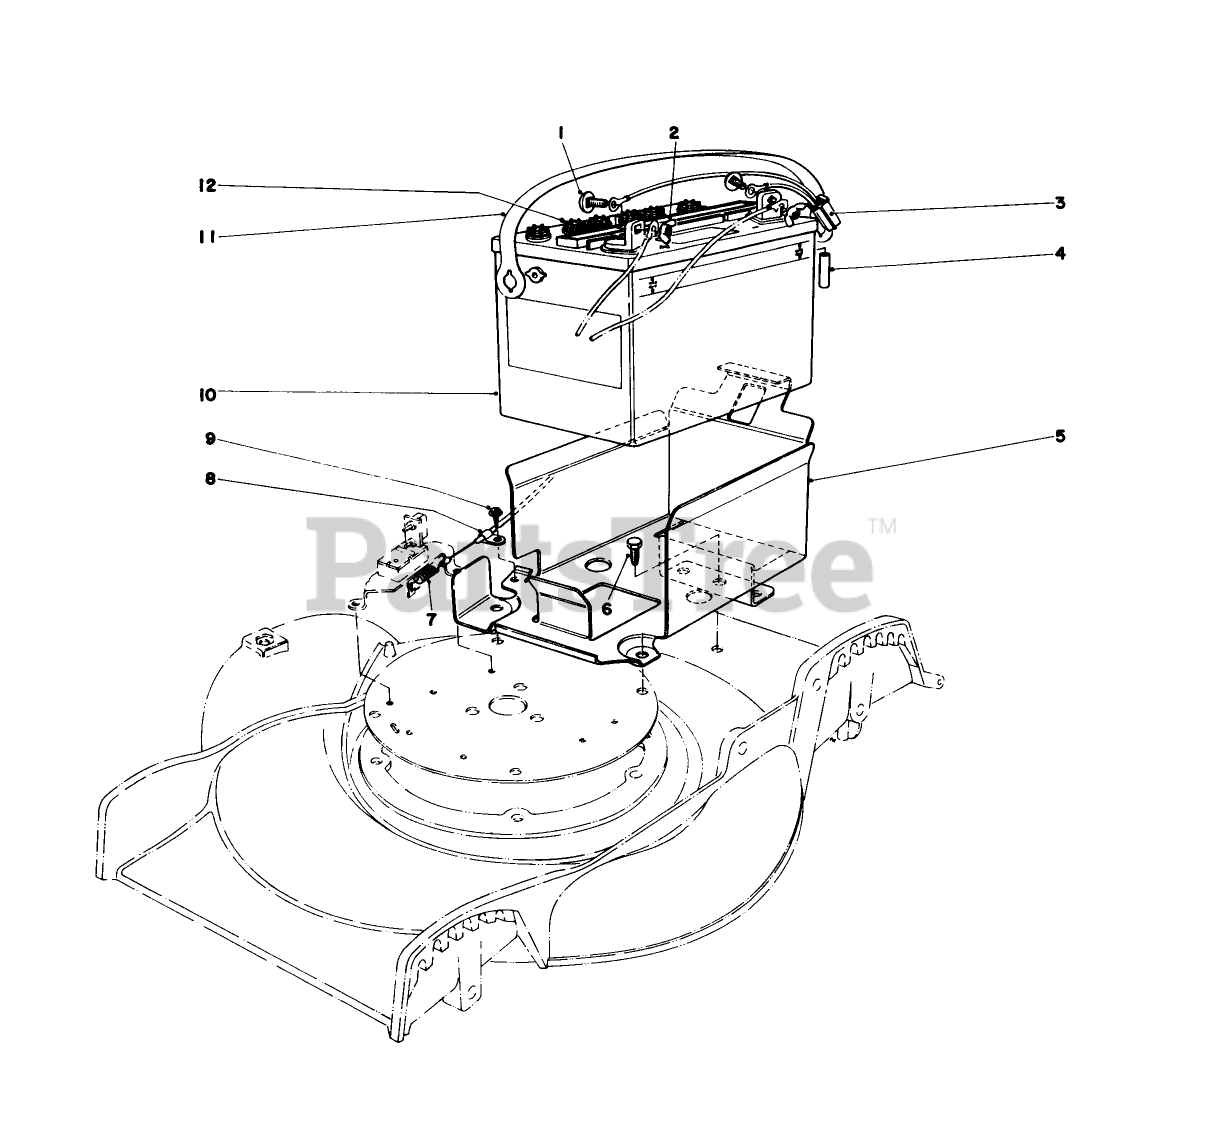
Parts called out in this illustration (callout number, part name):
1	Bolt-Carriage
2	NUT-WING
3	Battery Harness
4	Vent Tube
5	Battery Holder
6	SCREW-HWHTF
7	Control Cable Assembly
8	Clamp
9	SCREW-HWHTF
10	Battery (Incl. Ref. #1-3)
11	Carrying Strap
12	Vent Cap
